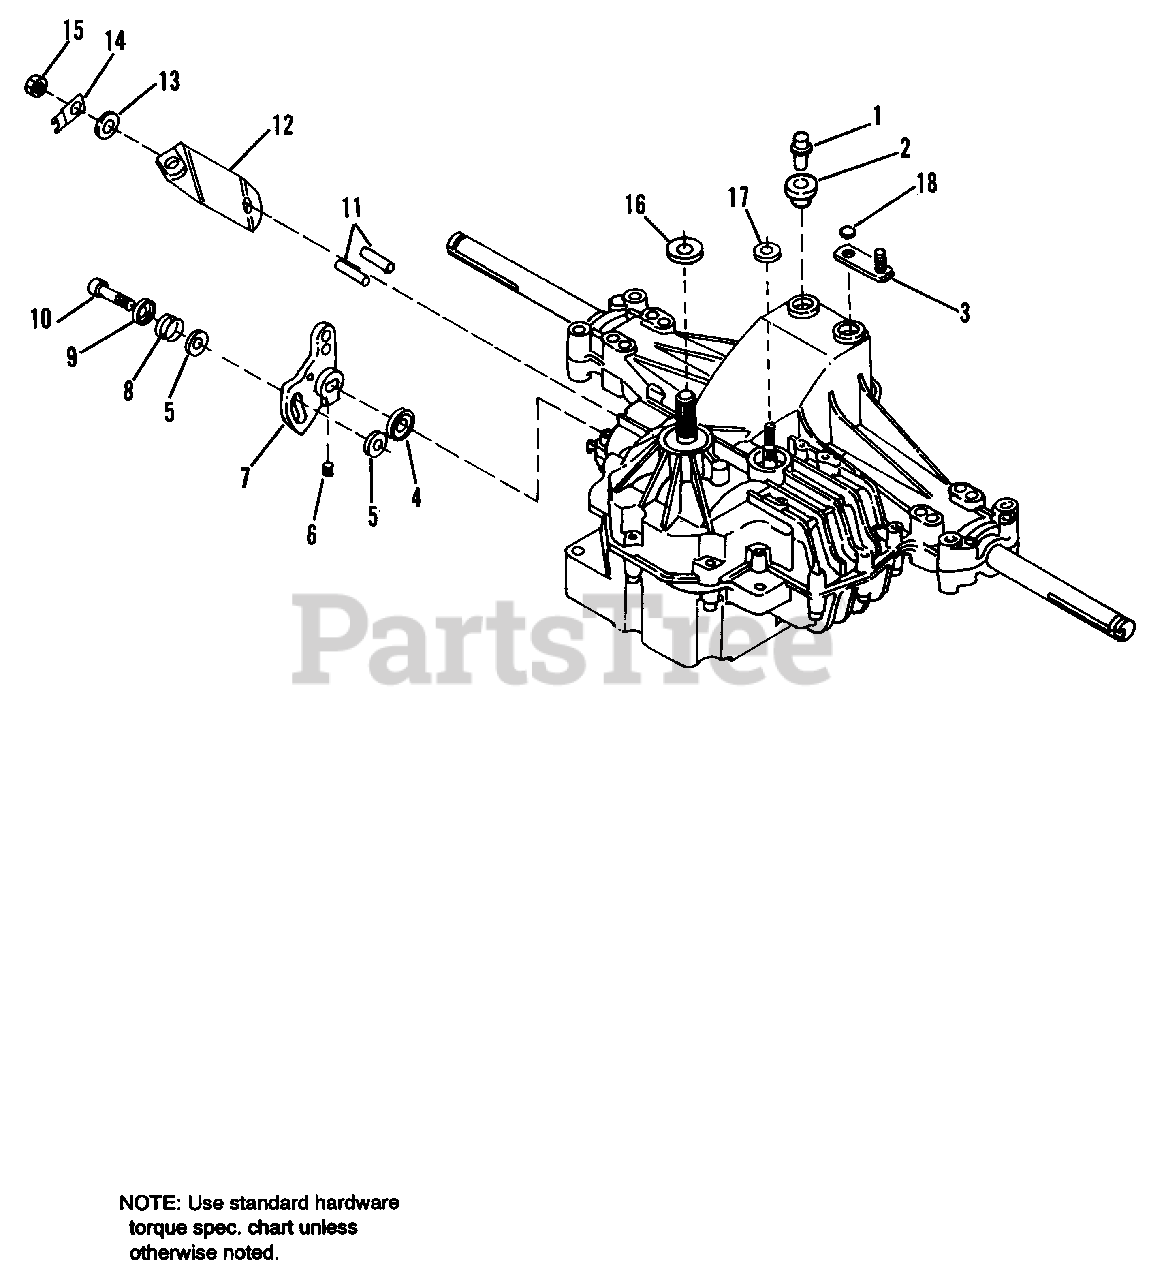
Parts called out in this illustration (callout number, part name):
1	BREATHER ASSY.
2	BUSHING, Rubber
3	ARM, Bypass
5	PUCK, Dampener
7	ARM, Control
10	SCREW, Soc. Hd.
11	ACTUATOR PIN
13	WASHER, 7/16 x 7/8 x 1/16
14	LOCKING STRAP
15	NUT, Hex Lock, 5/15 x 24
18	RING, Retaining
